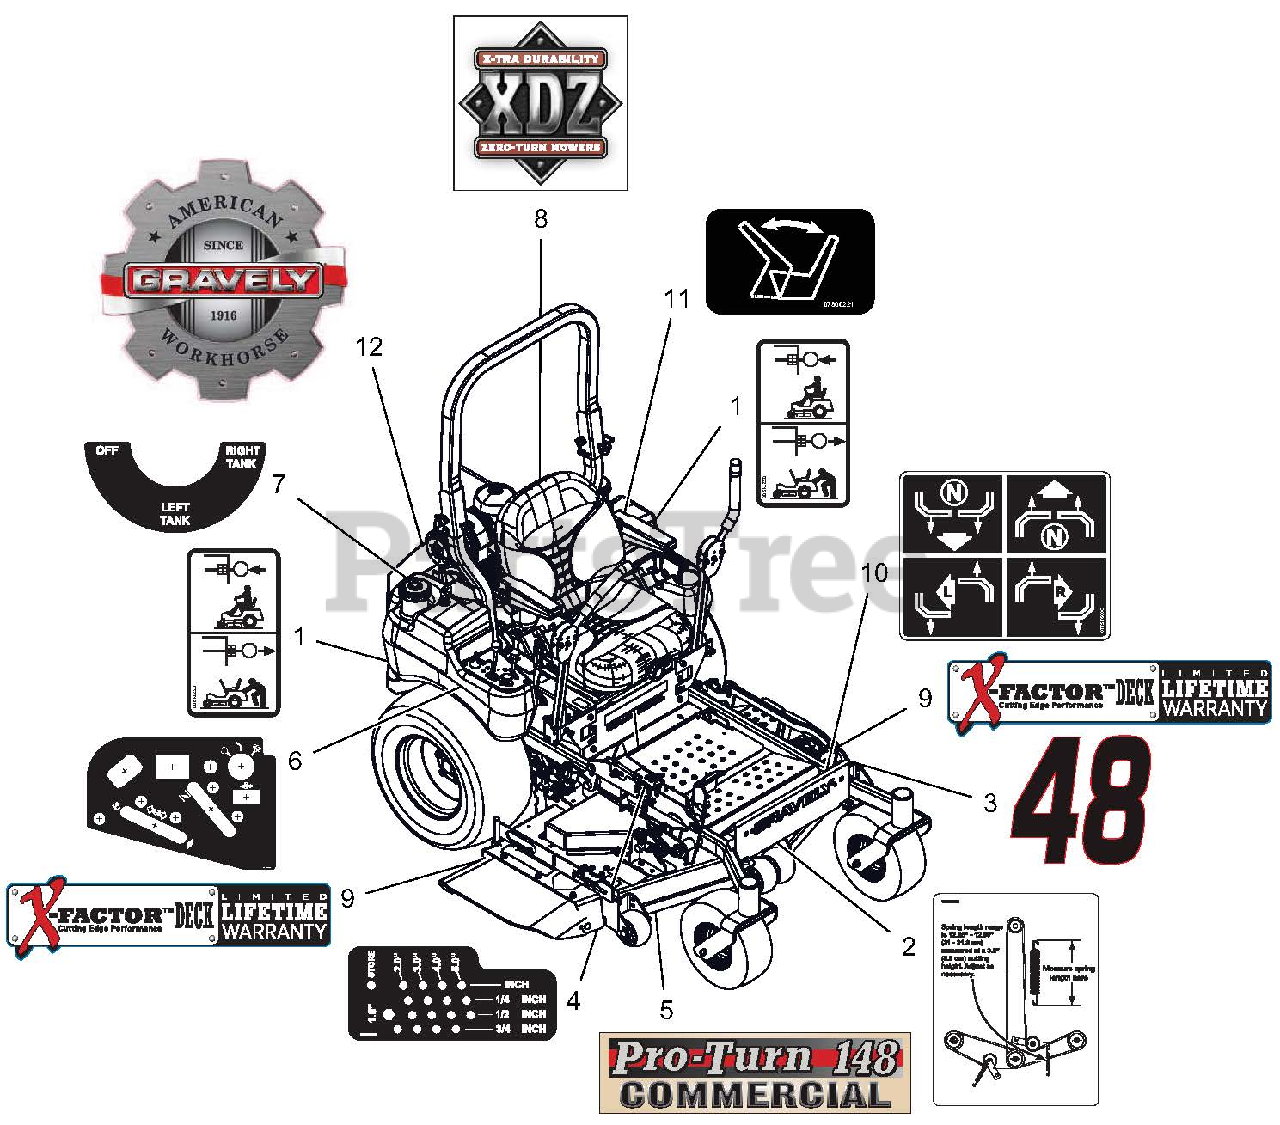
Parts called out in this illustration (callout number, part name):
1	DECAL, TRANSMISSION DISCONNECT
2	DECAL, BELT ROUTING
3	DECAL, 48"
4	DECAL, HEIGHT OF CUT
5	DECAL, PRO-TURN 148
6	DECAL, CONTROL PANEL
7	DECAL, FUEL VALVE
8	DECAL, XDZ
9	DECAL, X-FACTOR DECK
10	DECAL, INSTRUCTIONAL - STEERING
11	DECAL, SEAT RELEASE
12	DECAL, GRAVELY HERITAGE-LARGE
